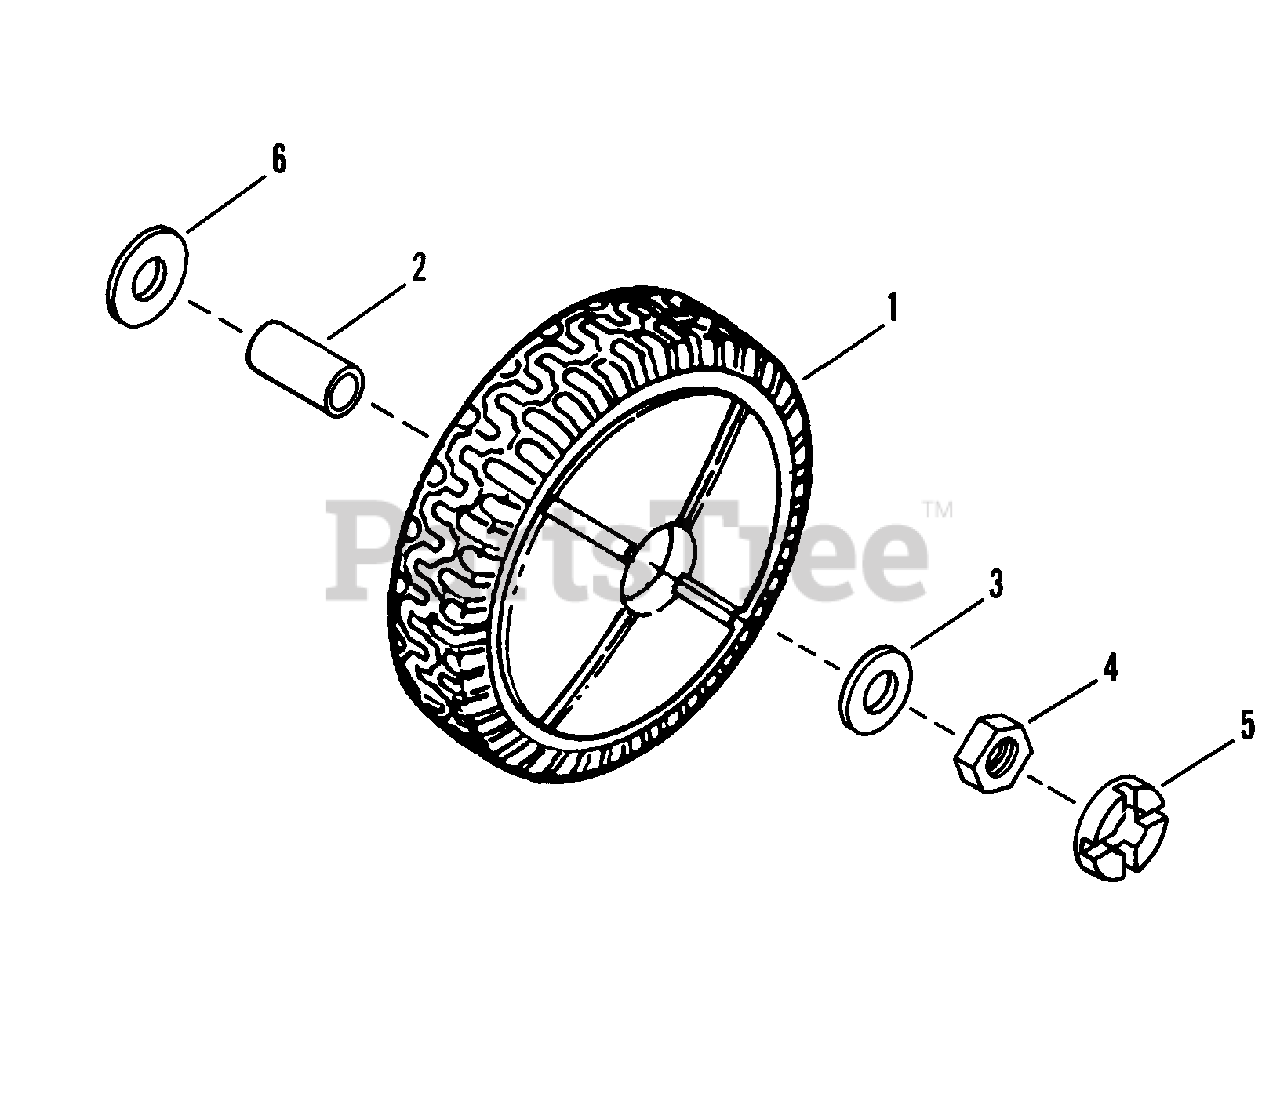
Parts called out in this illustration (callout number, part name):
1	WHEEL, 7 x 1.75, Plastic
2	BUSHING, Axle
3	WASHER, 7/16" ID x 1" OD SAE
4	NUT, 7/16-20 Hex (Thin)
5	PLUG, Wheel
6	WASHER, 1" O.D., Flat
